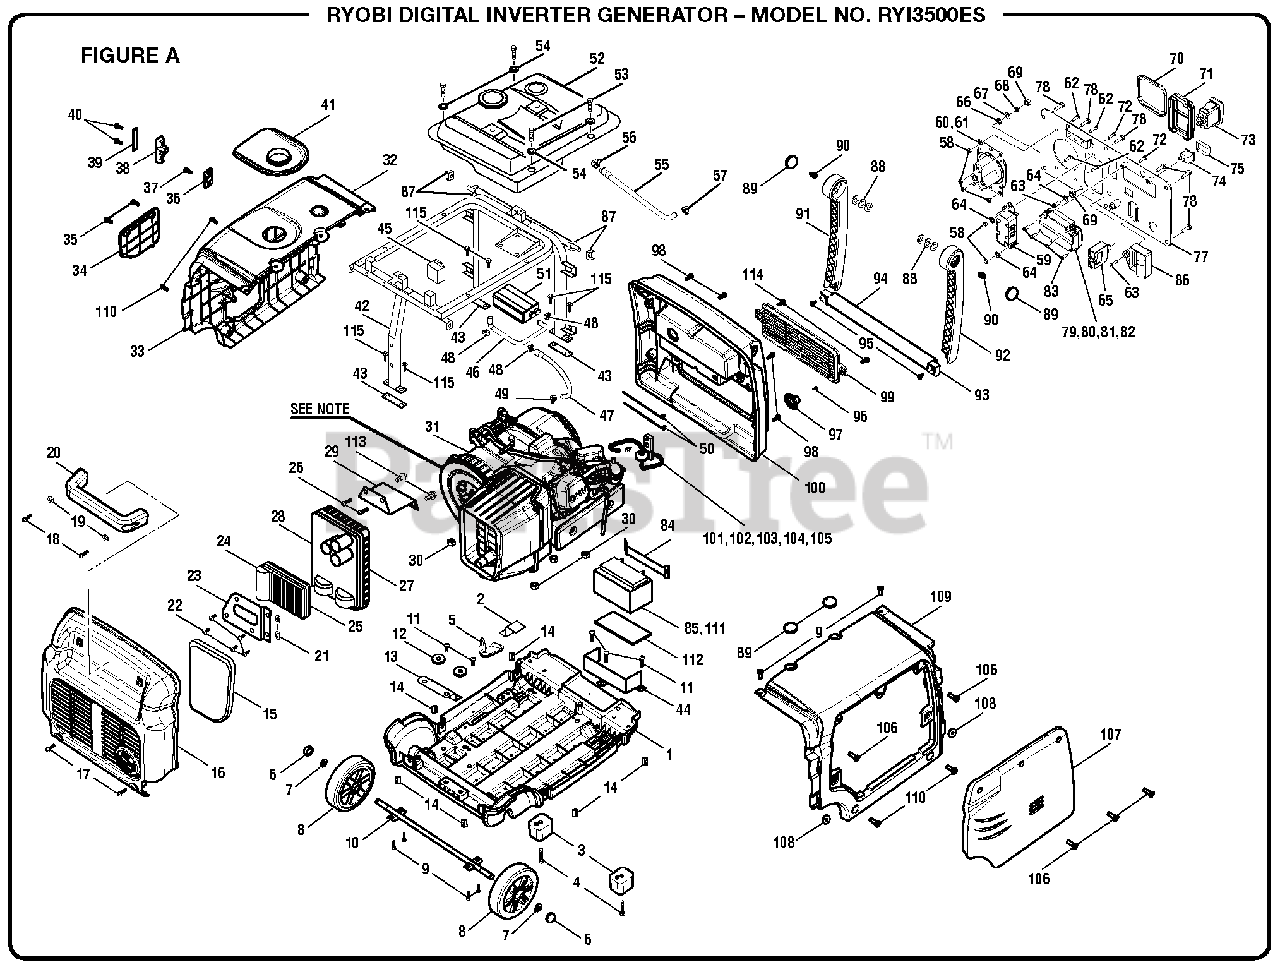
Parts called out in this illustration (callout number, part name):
1	Bottom Base
3	Rubber Feet
4	Screw (M5 x 30 mm, Pan Hd.)
5	Oil Drain Plug
7	Washer (M12)
9	Screw (M5 x 16 mm, Pan Hd.)
11	Screw (M5 x 12 mm, Pan Hd.)
12	Fuel Tank Isolator
13	Lower Bracket (Inverter Module)
14	Square Nut (M6)
15	Muffler Cover Strips
16	Rear Exhaust Housing
17	Flange Bolt (M6 x 20 mm)
18	Bolt (M6 x 35 mm, Hex. Soc. Hd.)
20	Rear Handle
22	Flange Bolt (M6 x 10 mm)
23	Start Module Bracket
24	Engine Start Module
25	Temperature Sensor
26	Screw (M6 x 25 mm, Pan Hd.)
27	Inverter Assembly (3.5Kw)
28	Inverter Grounding Harness
29	Inverter Module Bracket
30	Flange Nut (M8)
32	Right Side Housing
33	Sponge (5 x 5)
34	Oil Maintenance Door
35	Screw (M5 x 16 mm)
36	Recoil Start Cover
37	Screw (M5 x 10 mm, Pan Hd.)
38	Recoil Handle
39	Recoil Handle Top Cover
40	Screw (M2.9 x 9.5 mm)
41	Fuel Overspill Guard
43	Press Plate
44	Battery Tray
45	Main Internal Wiring
46	Fuel Tank Vent Hose
47	Canister Vapor Hose
48	Spring Clip (10.5)
49	Spring Clip (8)
51	Carbon Canister Assembly
53	Flange Bolt (M6 x 25 mm)
56	Fuel Hose Clamp (10.5)
57	Fuel Hose Clamp (9.0)
59	Duplex Receptacle (120 Volt 20 Amp)
60	Receptacle (120V 30A)
61	Wiring Harness (AC Output)
62	Screw (M4 x 12 mm, Pan Hd.)
63	Screw (M4 x 10 mm, Pan Hd.)
64	Star Washer
65	Circuit Breaker (20A)
66	Star Washer
68	Lock Washer
70	Outlet Cover
71	Rain Cover (120V Receptacle)
72	Screw (M4 x 10 mm, Pan Hd.)
73	Engine Switch
75	Waterproof Cap
77	Electrical Faceplate
78	Screw (M5 x 12 mm, Pan Hd.)
79	Upper Cover Display Installation
80	Lower Cover Display Installation
81	Digitial Display
82	Soundproof Cotton, Display
83	Screw (M4 x 16 mm, Pan Hd.)
84	Battery Hold Down
86	Ignition Assembly
87	Saddle Washer (M12)
89	Rubber Plug
90	Flange Nut (M6)
91	Right Front Handle
92	Left Front Handle
93	Front Handle Pull Bar
94	Recoil Handle Rubber
95	Bolt Flange (M6 x 12 mm)
96	Screw (M4 x 16 mm, Pan Hd.)
97	Fuel Valve Control Knob
98	Flange Bolt (M6 x 20 mm)
99	Battery Maintenance Cover
100	Front Housing
102	Fuel Hose Fuel Valve
103	Fuel Filter Inline (1/4 in.)
104	Fule Filter Fuel Hose
105	Fuel Hose Clamp (8.0)
106	Flange Bolts (M6 x 16 mm)
107	Air Cleaner Maintenance Cover
108	Rubber Grommet
109	Left Side Housing
110	Flange Bolt (M6 x 16 mm)
111	Battery Wire Harness
112	Rubber Battery Pad
113	Screw
114	Screw
115	Screw
